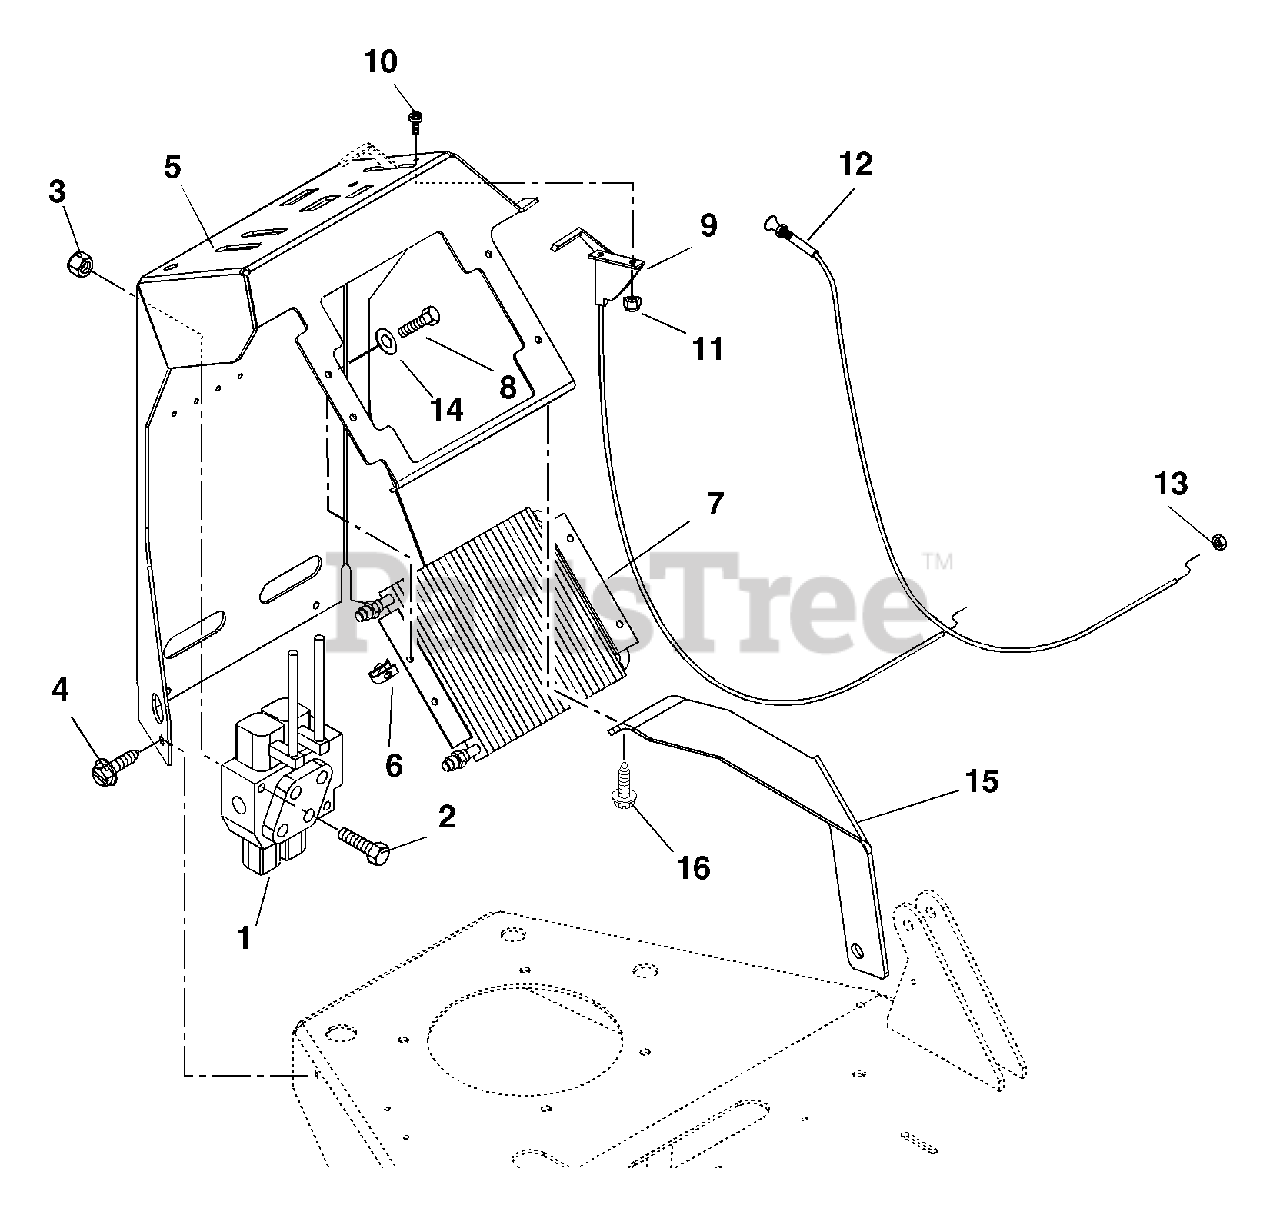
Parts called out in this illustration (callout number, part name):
1	Valve, 2 Spool
2	Bolt-Hex .31-18 x 1.75 Grade 5
3	Nut-Locking-Nylon .31-18
4	Screw-Tapping .38-16 x .75 Hex Washer Head
5	Panel, Control
6	Nut-Retainer .25-20 x .56
7	Cooler, Oil
8	Bolt-Hex .25-20 x .75 Grade 5
9	Cable, Throttle
10	Screw-Machine 10-24 x .50 Hex Washer Head
11	Nut-Locking-Nylon 10-24 with Insert
12	Cable, Choke
13	Nut-Jam .38-24
14	Washer-Flat-Steel .28 x .62 x .065
15	Brace, Instrument Panel-Left Hand
16	Screw-Tapping .25-20 x .50 Hex Washer Head
